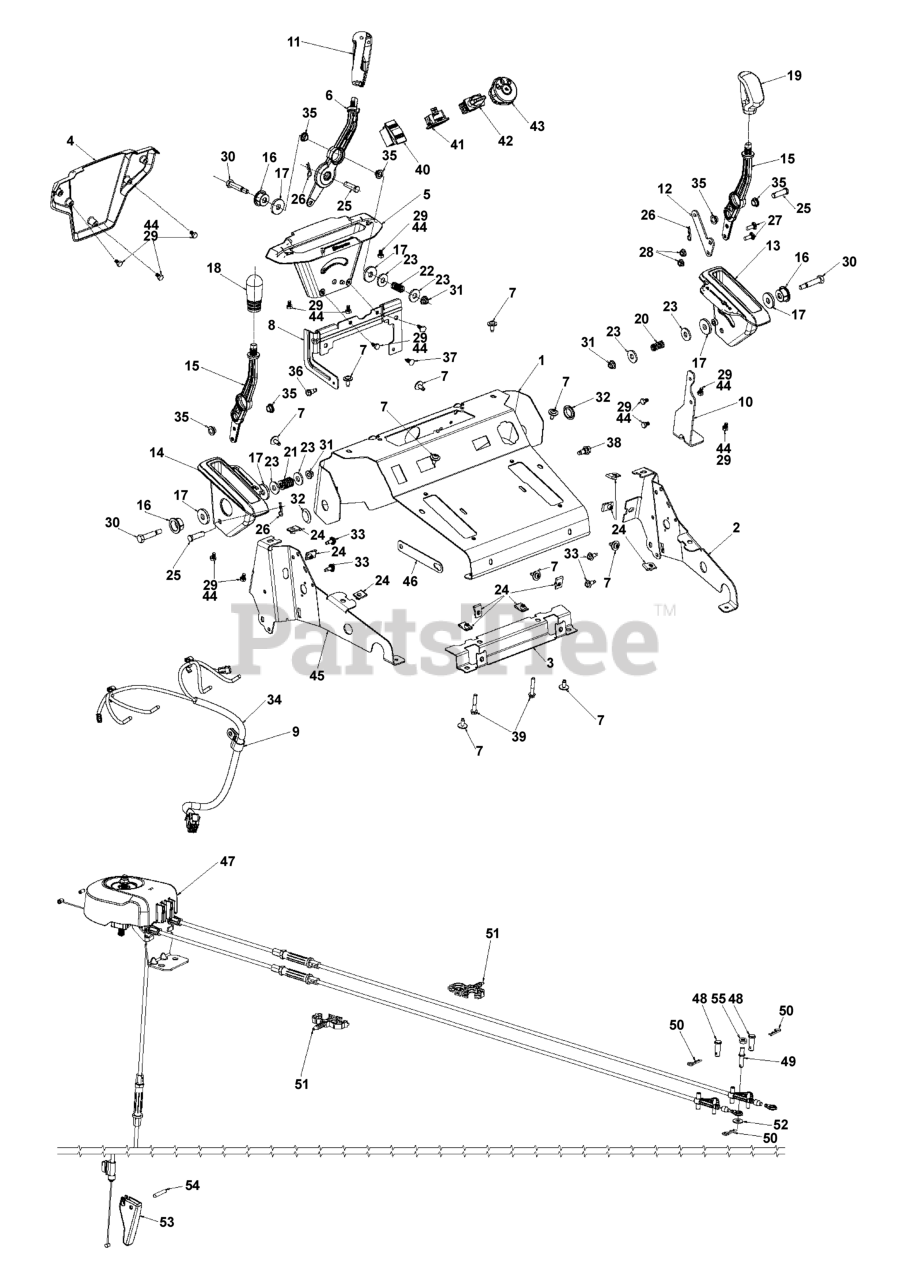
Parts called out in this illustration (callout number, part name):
6	LEVER CHUTE ROTATOR 400S CHUTE
8	Brackets
8	BRACKET CABLE CHUTE ROTATOR
9	CLIP.CABLE.BLK
24	NUT.U-CHNL.1/4-20.550DP.350PNL
26	HAIRPIN.SOFT.ZINC.059X1.125
27	BOLT CUP HEAD SQUARE NECK BOLT
28	NUT.HEX.FLANGE.1/4
31	NUT HEXAGON FLANGE 5/16-18 ST
33	SCREW 14-20 X 5/8
33	HEX.WASHER.HEAD 1/4-20 X .65
34	Harnesses
34	HARNESS
36	BOLT SHOULDER_1/4-20_TRILOB
37	FASTENER.PUSH.O.250X0.783
38	SHOULDER BOLT 5/16-18TT
39	SCREW.HEXCAP.1/4X-20X1.500
40	SWITCH HEATED GRIP BLK
41	HOUR METER SNAPIN, RECTANGULAR
42	SWITCH 3 POSITION ROTARY
43	SWITCH IGNITION 3 POSITION 6-W
46	SUPPORTS
46	Braces
47	CABLE CHUTE ROTATOR ASM LOCKIN
47	Cables
48	PIN CLEVIS 5/16X.875
49	Clevis Pins
50	HAIRPIN.SOFT.ZINC.059X1.125
51	CLIP.CONDUIT.DOUBLE LOOP
52	WASHER FLAT_.250 X .625 X .06
54	PIN, ROLL 3/16 X 1-1/8
55	NUT HEXAGON 1/4-20 ST ZPB
